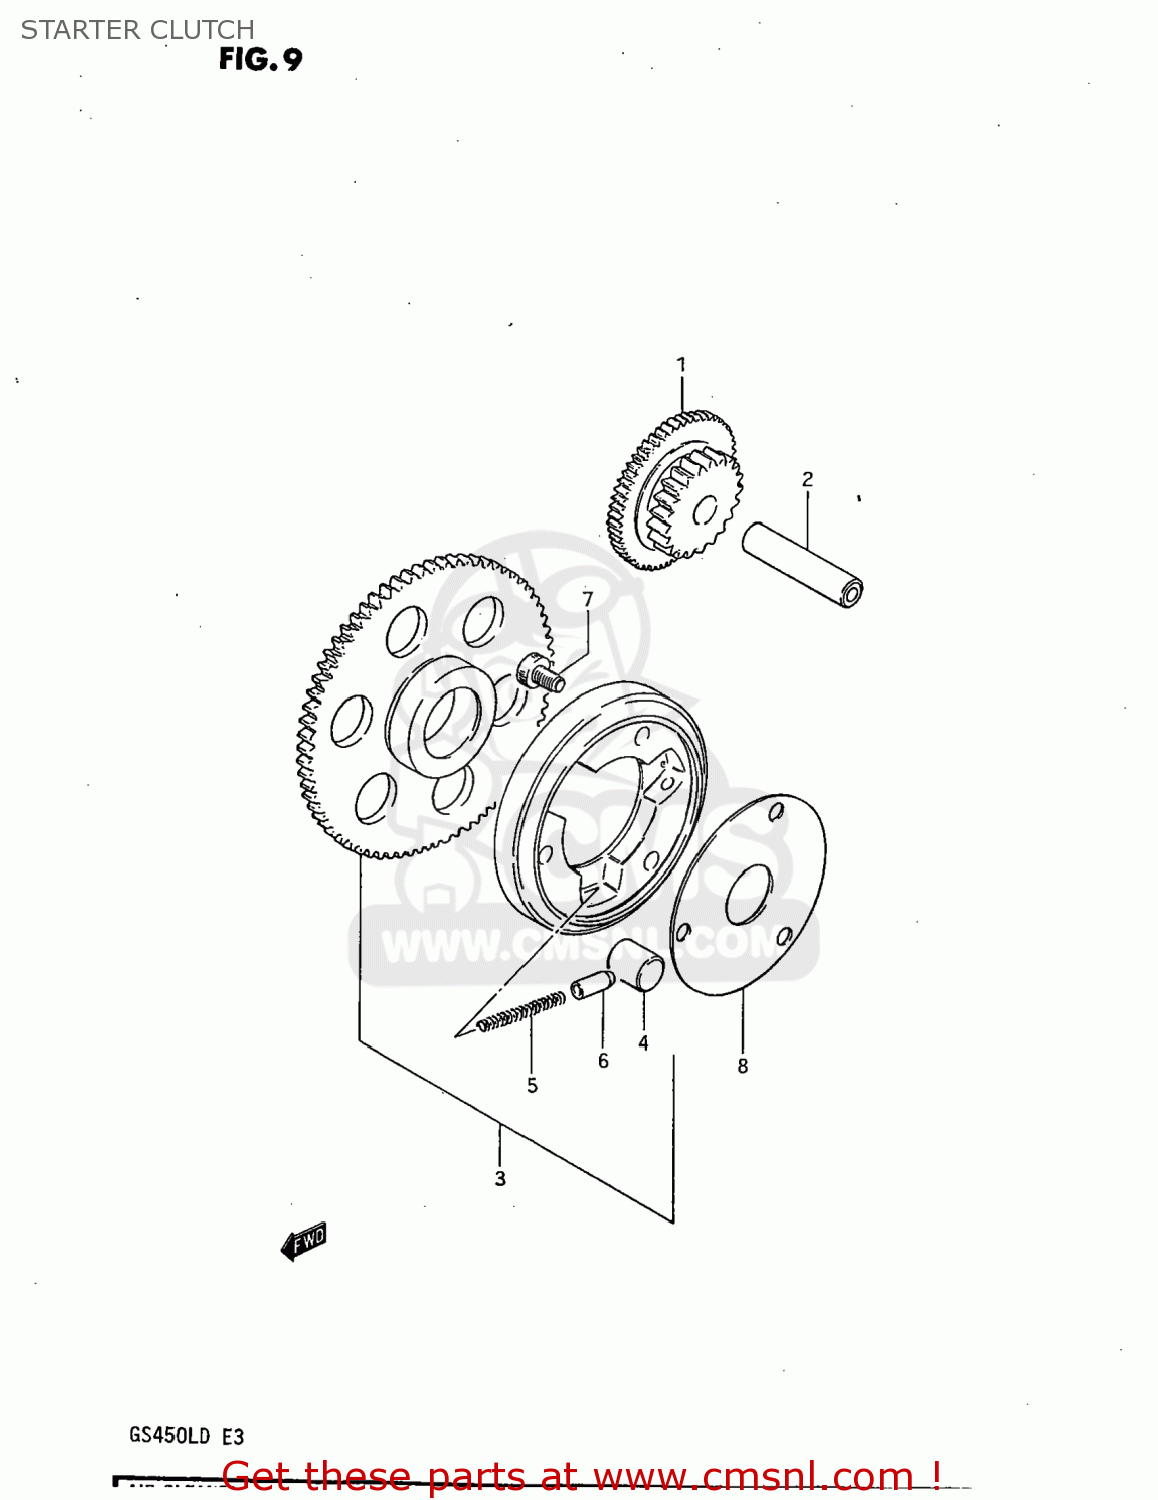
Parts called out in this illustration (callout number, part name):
1	GEAR,STARTER IDLE
2	PIN(7.4X13X56)
3	CLUTCH SET,STARTER
4	ROLLER(15X13)
5	SPRING
6	PIECE,PUSH
7	BOLT
8	SHIM,STARTER CLUTCH HUB
